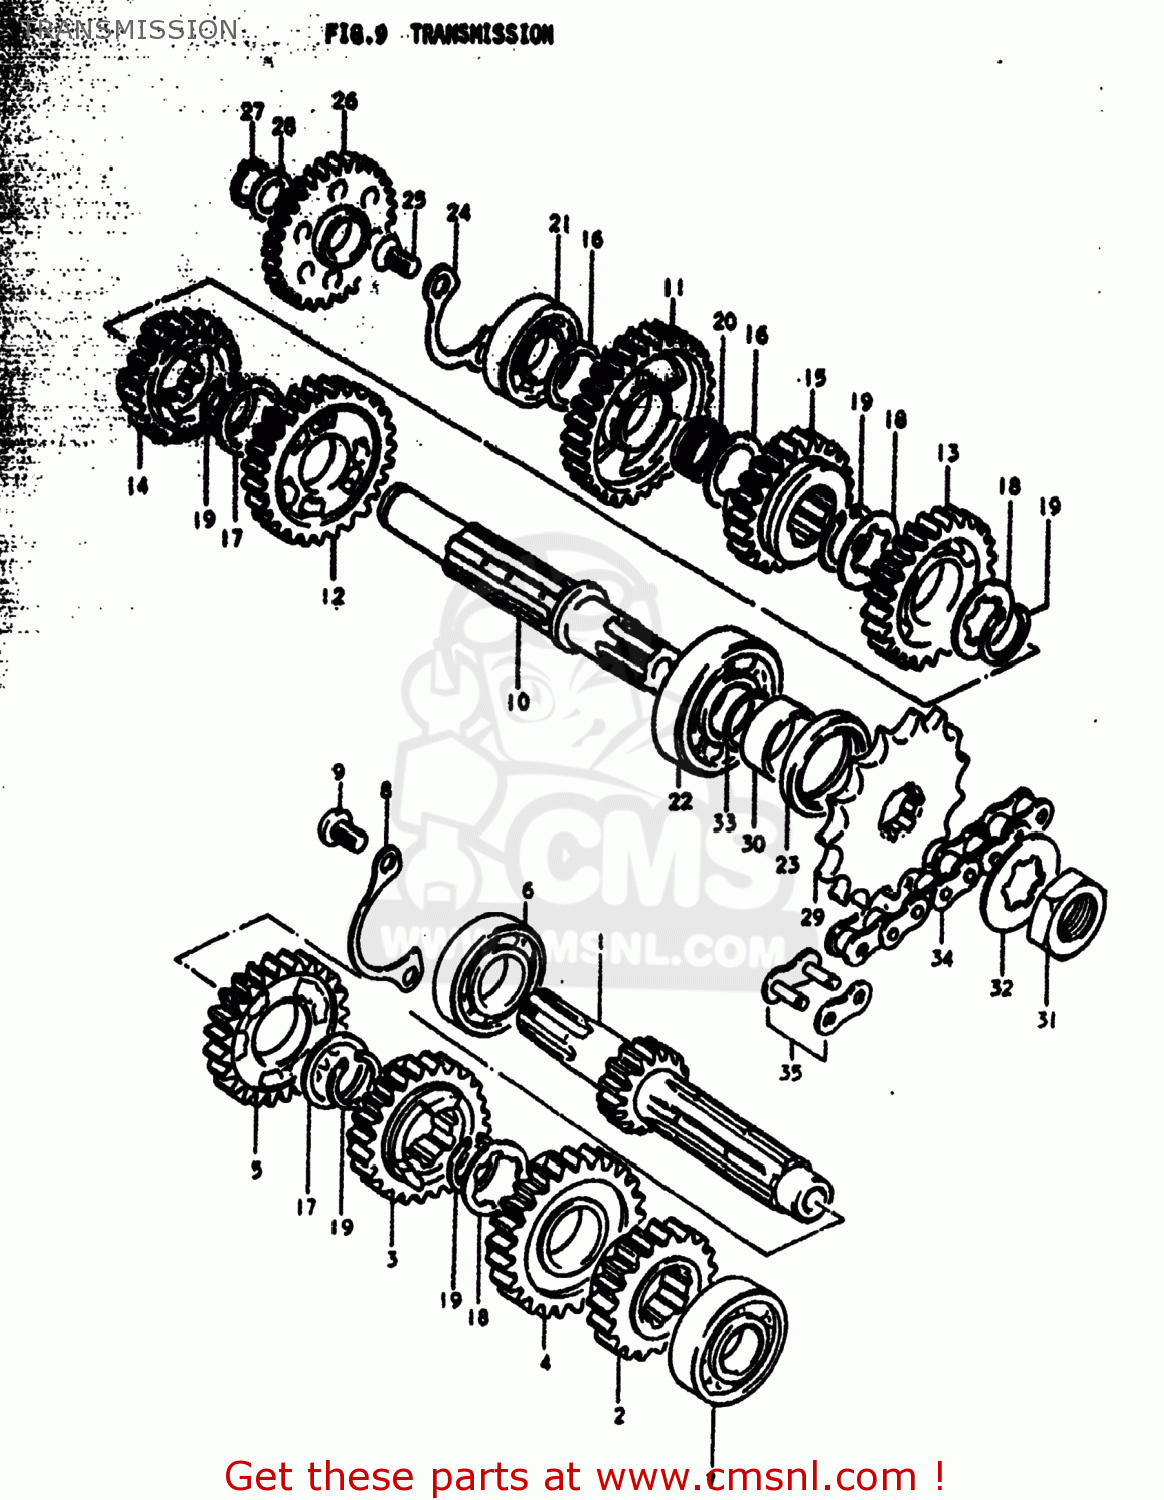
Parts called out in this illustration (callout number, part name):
1	SHAFT,COUNTER
2	GEAR,SECOND DRIVE
3	GEAR,THIRD DRIVE
4	GEAR,FOURTH DRIVE
5	GEAR,FIFTH DRIVE
6	BEARING
7	BEARING
8	PLATE,COUNTERSHAFT BEARING
9	SCREW 6X12
10	SHAFT,DRIVE
11	GEAR,FIRST DRIVEN
12	GEAR,SECOND DRIVEN
13	GEAR,THIRD DRIVEN
14	GEAR,FOURTH DRIVEN
15	GEAR,FIFTH DRIVEN
16	WASHER
17	SHIM(22X28X0.5)
18	WASHER,LOCK
19	CIRCLIP
20	BEARING(17X21X9.8)
21	BEARING
22	BEARING
23	SEAL,OIL(32X42X6)
24	PLATE,DRIVESHAFT BEARING
25	SCREW
26	GEAR,KICK STARTER IDLE
27	CIRCLIP
28	WASHER
29	SPROCKET,ENGINE
30	SPACER(22X32X11.5)
31	NUT
32	WASHER,LOCK
33	O RING(D:1.7,ID:22)
34	CHAIN ASSEMBLY,DRIVE
35	JOINT ASSEMBLY,CHAIN
